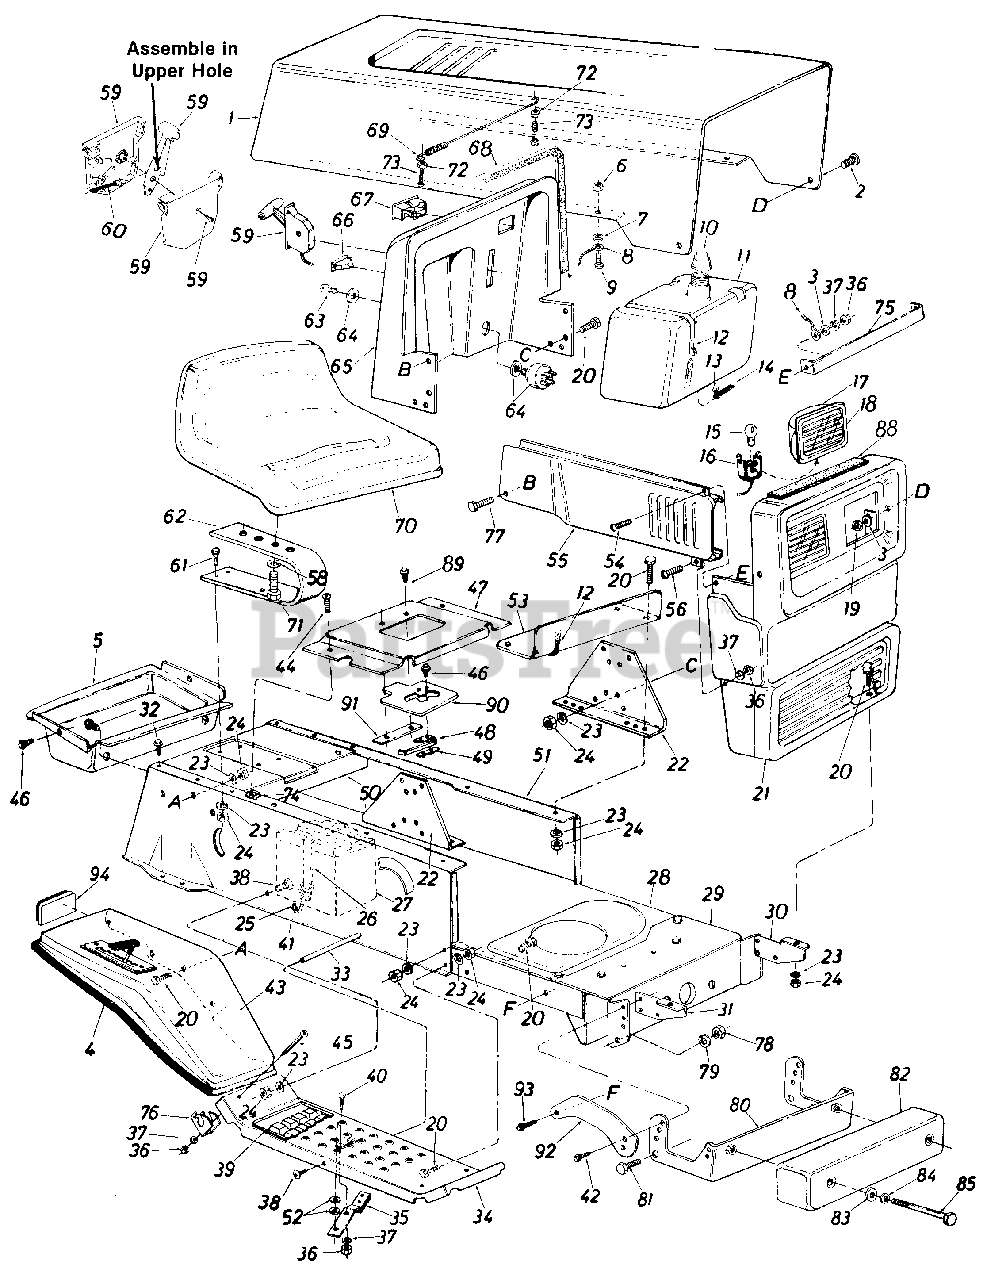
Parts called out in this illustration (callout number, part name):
1	Hood
2	Truss Hex Scr. 1/4-20 x .62" Lg.
3	Fl-Wash. .296" I.D. x .62" O.D.
4	Trim Strip 27"
5	Tool Tray
6	Hex Sems Nut #10-24 Thd.
7	Fl-Wash. .203" I.D. x .41" O.D. x .040
8	Hood Stop
9	Truss Hd. Scr. #10-24 x 1/2" Lg.*
10	Fuel Cap Gauge
11	Fuel Tank
12	Tie Strap
13	Hose Clamp
14	Fuel Line
15	Lam p
16	Socket
17	Headlight Housing
18	Lens
19	Hex L-Nut 1/4-20 Thd.
20	Hex Bolt 5/16-18 x .75" Lg.
21	Grille
22	Dash Support Bracket
23	L-Wash. 5/16" I.D.
24	Hex Nut 5/16-18 Thd.
25	Battery Strap Hook
26	Battery Hold Down Strap
27	12V Battery
28	Lower Frame
29	Front Pivot Brk't.
30	Grille Mount Brk't L.H.
33	Running Board Rod
34	Running Board
35	Blade Brake Ass'y.
36	Hex Nut 1/4-20 Thd.
37	L-Wash. 1/4" I.D.
38	Truss Mach. Scr. 5/16-18 x .75" Lg.
39	Foot Pad
40	Carriage Bolt 1/4-20 x .62" Lg.
41	R.H. Side Frame
42	Hex Wash. Hd. TT-Tap Scr. 5/16 x 1.0" Lg.
45	Truss Hd. Scr. 1/4-20 x 1.75" Lg.
46	Truss Hd. Scr. #10-24 x .50"
47	Transmission Panel
48	Reverse Safety Switch
49	Insulator Nut Plate
50	Hitch Plate
51	L.H. Side Frame
52	Fl-Wash. .28" I.D. x .75" O.D. x .06
53	Fuel Tank Support
54	Truss Hd. Scr. 1/4-20 x .75" Lg.*
55	Side Cover R.H.
56	Truss Mach. Scr. 1/4-20 x .50" Lg.
58	L-Wash. 1/2" I.D.
59	Throttle Control Box Ass'y.
60	Throttle Control Wire
61	Hex Bolt 5/16-18 x 1.00" Lg.*
62	Seat Spring 5.5" High
63	Ignition Key
64	Ignition Switch
65	Dash Panel
66	Light Switch
67	Ammeter
68	Trim Strip 27"
69	Hood Spring
70	Seat Ass'y.
71	Hex Bolt 1/2-13 x 1.0" Lg.
72	Hex Top L-Nut #10-24
73	Hex Bolt #10-24 x 1.0" Lg.
74	Speed Nut #10Z
75	Tie Strap GrillelSide Panel
76	Fender Clamp
77	Hex Wash. Hd. Tap Scr. 1/4 x .75" Lg.
78	Hex Nut 7/16-14 Thd.
79	L-Wash. 7/16" I.D.
80	Weight Brk't. Ass'y.
81	Hex Bolt 7/16-14 x 1.0" Lg.
82	Counter Weight 38#
83	Fl-Wash. .39" I.D.
84	Bell-Wash. .39" I.D.
85	Hex Bolt 3/8-16 x 4.5" Lg.
88	Foam Strip 3/8 x 1 x 14" Lg.
89	Truss Mach. Scr. 1/4-20 x .75" Lg.
90	Gear Selection Plate
91	Clamping Plate
92	Weight Brk't. Tie Strap
93	Hex Wash. Hd. Tap Screw 3/8-16 x .88" Lg.
94	Reflector
